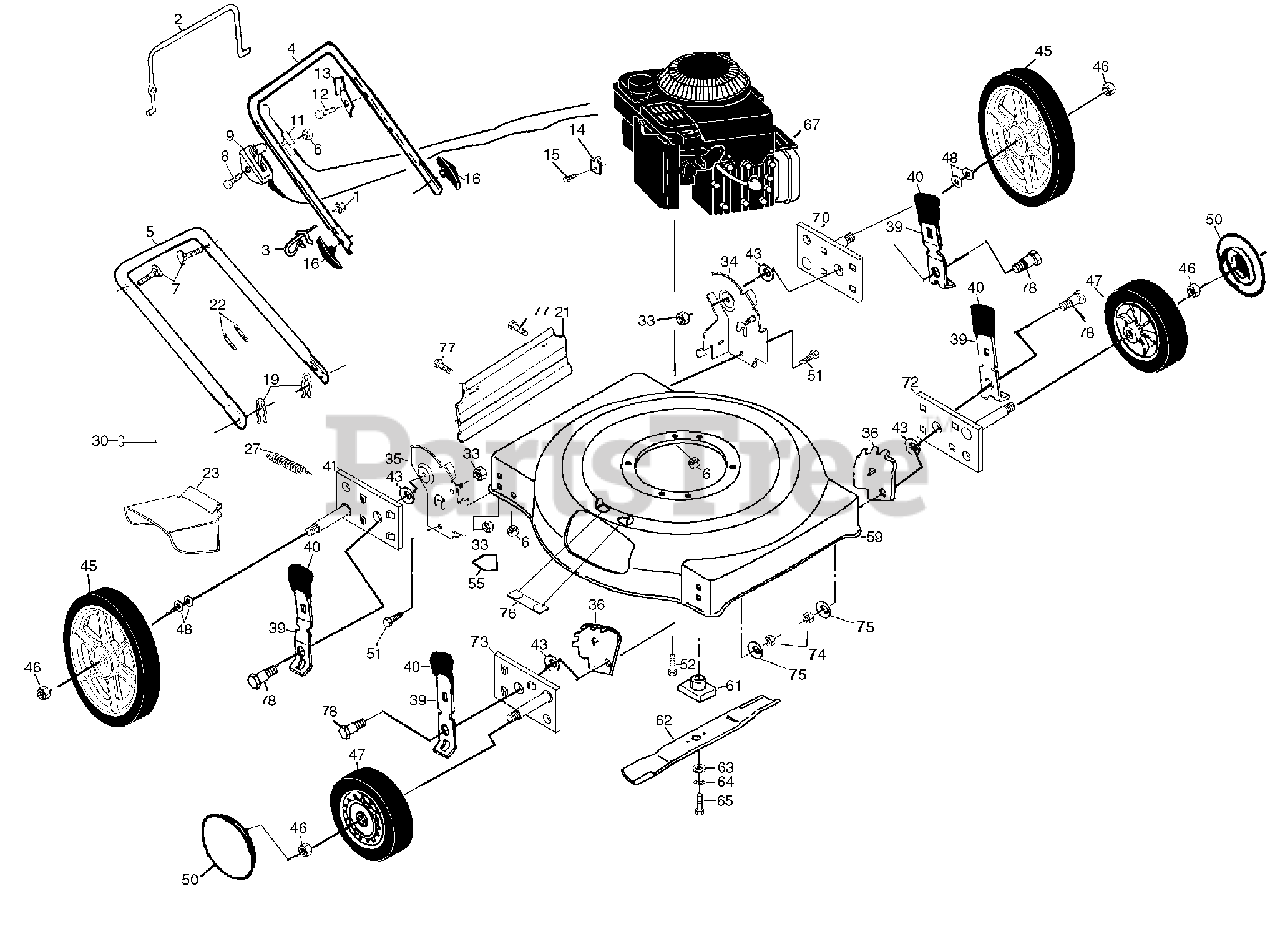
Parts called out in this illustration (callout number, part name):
1	Locknut 1/4-20
2	Control Bar
3	Rope Guide
4	Upper Handle
5	Lower Handle
6	Locknut 1/4-20
7	Handle Bolt 5/16-18
8	Hex Washer Head Screw 1/4-20 x 2-1/8
9	Throttle Control
11	Engine Zone Control Cable
12	Hex Washer Head Screw #10-24 x 1/2
13	Up-Stop Bracket
14	Cable Clamp
15	Screw #10 x 5/8
16	Handle Knob
19	Hairpin Cotter
21	Rear Deflector
22	Wire Tie
23	Discharge Guard
27	Torsion Spring
30	Hinge Rod
33	Locknut 5/16-18
34	Wheel Bracket Support (Left)
35	Wheel Bracket Support (Right)
36	Wheel Bracket Adjuster
39	Selector Spring
40	Selector Knob
41	Axle Arm Assembly (RR)
43	Washer
45	Wheel Assembly (Rear)
46	Locknut 1/16-18
47	Wheel Assembly (Front)
48	Washer
50	Hubcap
51	Hex Head Bolt 5/16-18
52	Hex Head Thread Rolling Screw 3/8-16 x 1
55	Danger Decal
59	Lawn Mower Housing
61	Blade Adapter
62	22" Blade
63	Hardened Washer
64	Helical Lockwasher 3/8
65	Screw Hex Head 3/8-24 x 1-3/8 (Grd. 8)
70	AxleArm Assembly (LR)
72	AxleArm Assembly (LF)
73	Axle Arm Assembly (RF)
74	Nut
76	Clip, Closeout
77	Screw
78	Shoulder Bolt
78	Operator's Manual (English)
78	Replacement Parts Manual
78	Grass Catcher
78	Mulcher Kit
